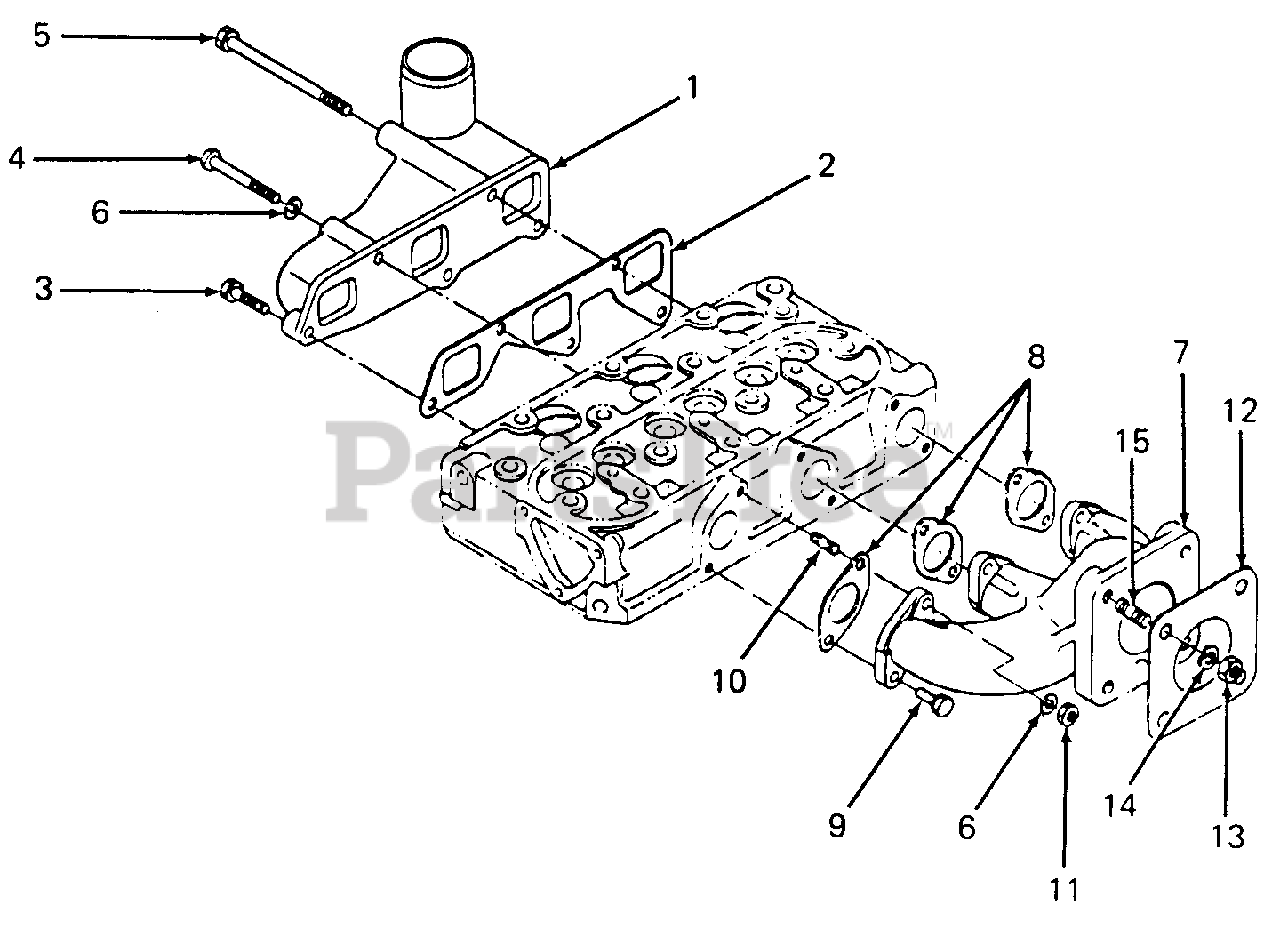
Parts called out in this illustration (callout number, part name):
1	Manifold, Inlet
2	Gasket, Inlet Manifold
3	Screw, Hex Cap
4	Screw, Hex Cap
5	Screw, Hex Cap
6	Washer, Spring
7	Manifold, Exhaust
8	Gasket, Exhaust Manifold
9	Screw, Hex Cap
12	Gasket
14	Washer, Spring
